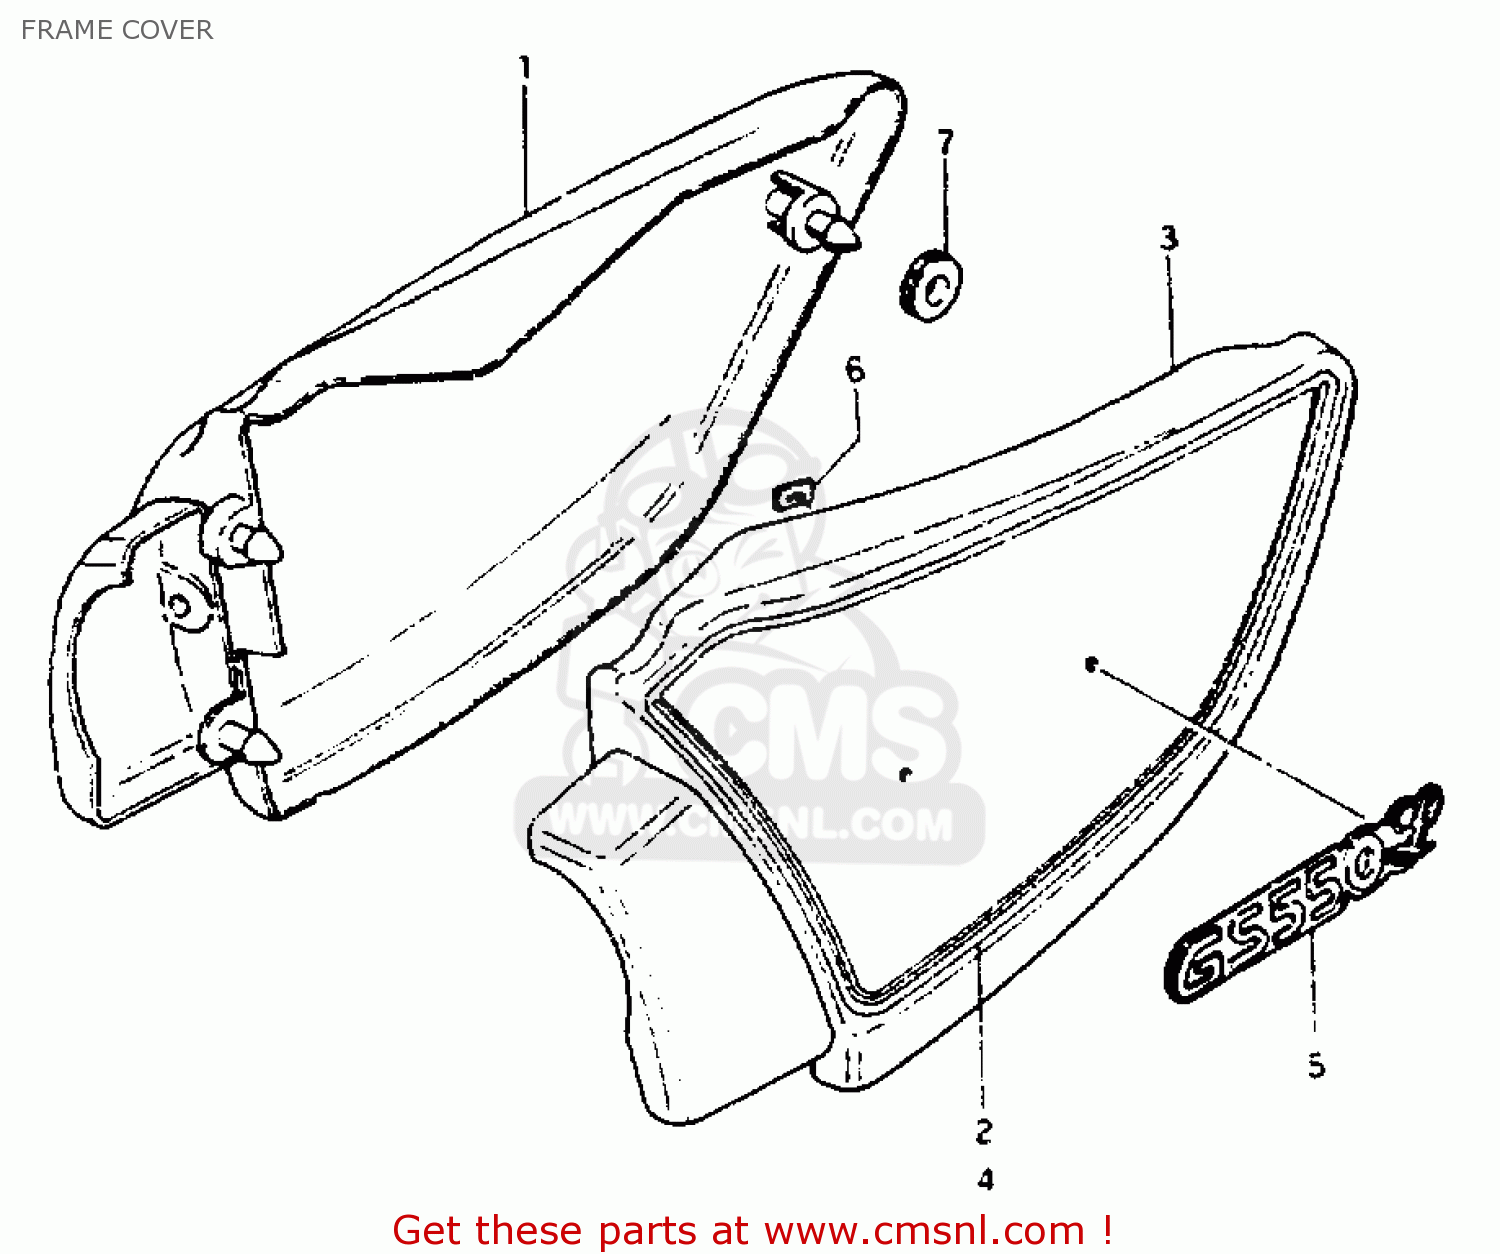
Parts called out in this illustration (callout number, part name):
1	COVER,FRAME,RIGHT
2	TAPE SET,FRAME COVER
3	COVER,FRAME,LEFT
4	TAPE SET,FRAME COVER
5	EMBLEM,FRAME COVER
6	NUT
7	CUSHION
